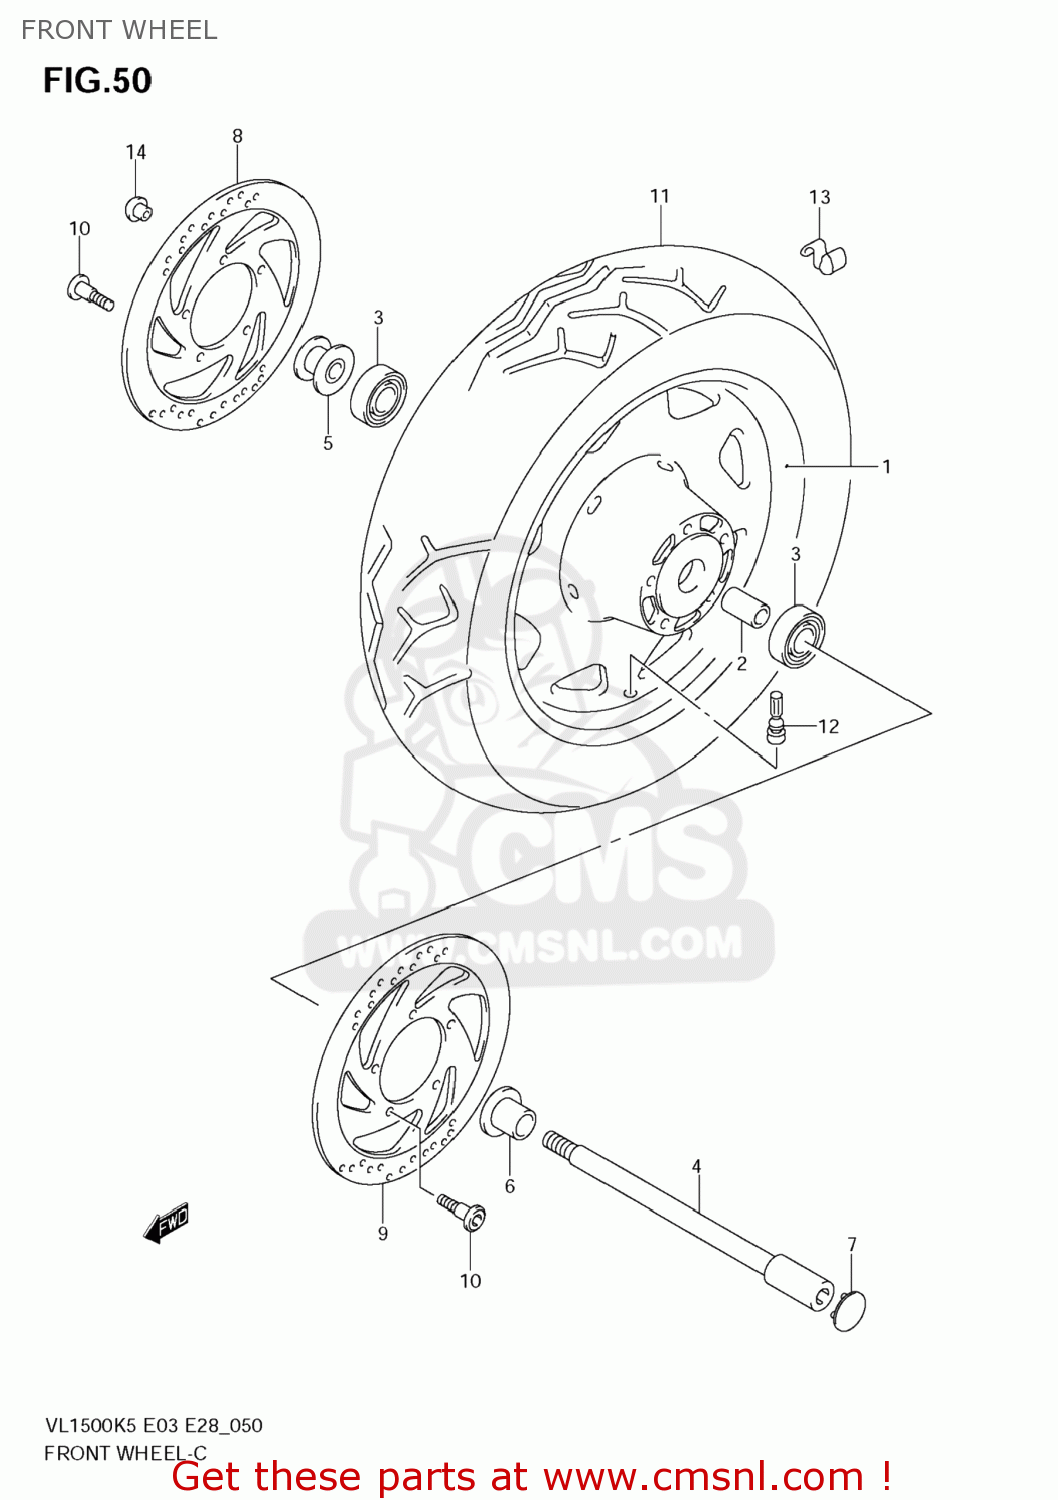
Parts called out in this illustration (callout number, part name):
1	WHEEL,FR(16XMT3.50)
2	SPACER,FR HUB BEARING
3	BEARING
4	AXLE,FR
5	SPACER,FR AXLE,R
6	SPACER,FR AXLE,R
7	CAP,FR AXLE
8	DISC,FR BRAKE,R
9	DISC,FR BRAKE,L
10	BOLT(8X33)
11	TIRE,FR
12	VALVE ASSY,WHEEL RIM(TR412)
13	WEIGHT,WHEEL BALANCE 10G
14	CAP,FR AXLE
